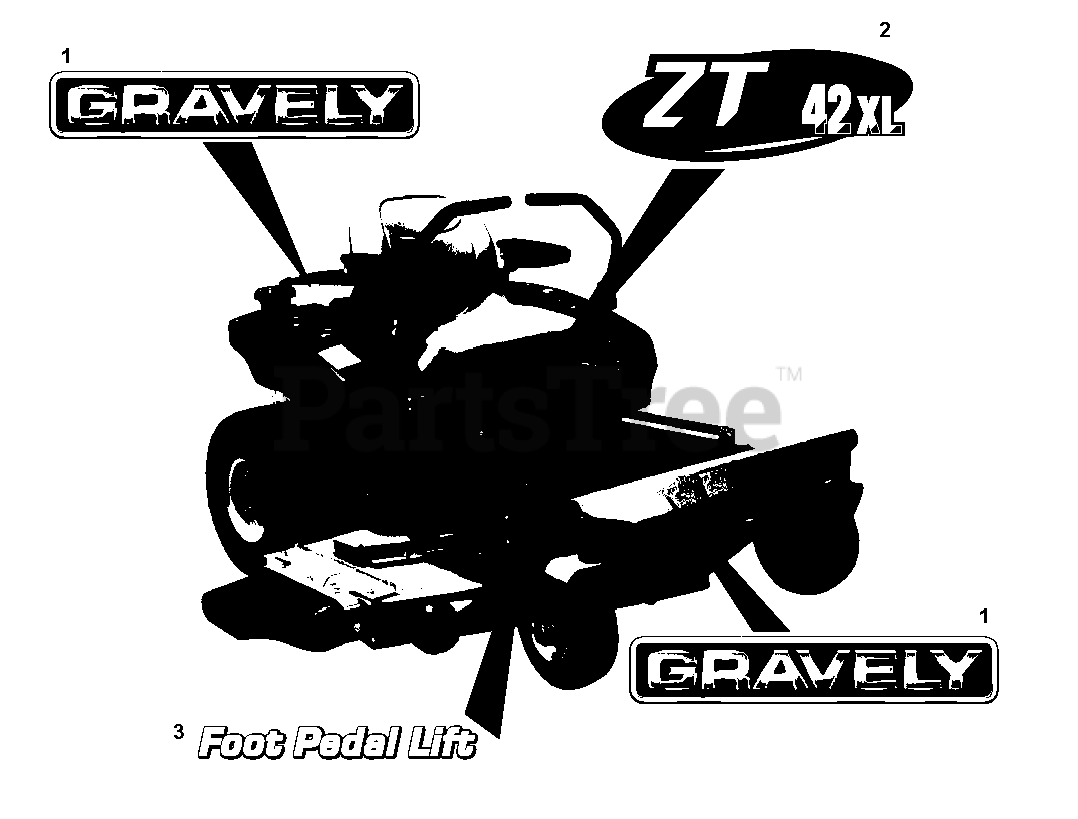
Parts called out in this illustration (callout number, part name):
1	Decal, Gravely Logo
2	Decal, 42 ZT XL
3	Decal, Foot Pedal Lift
